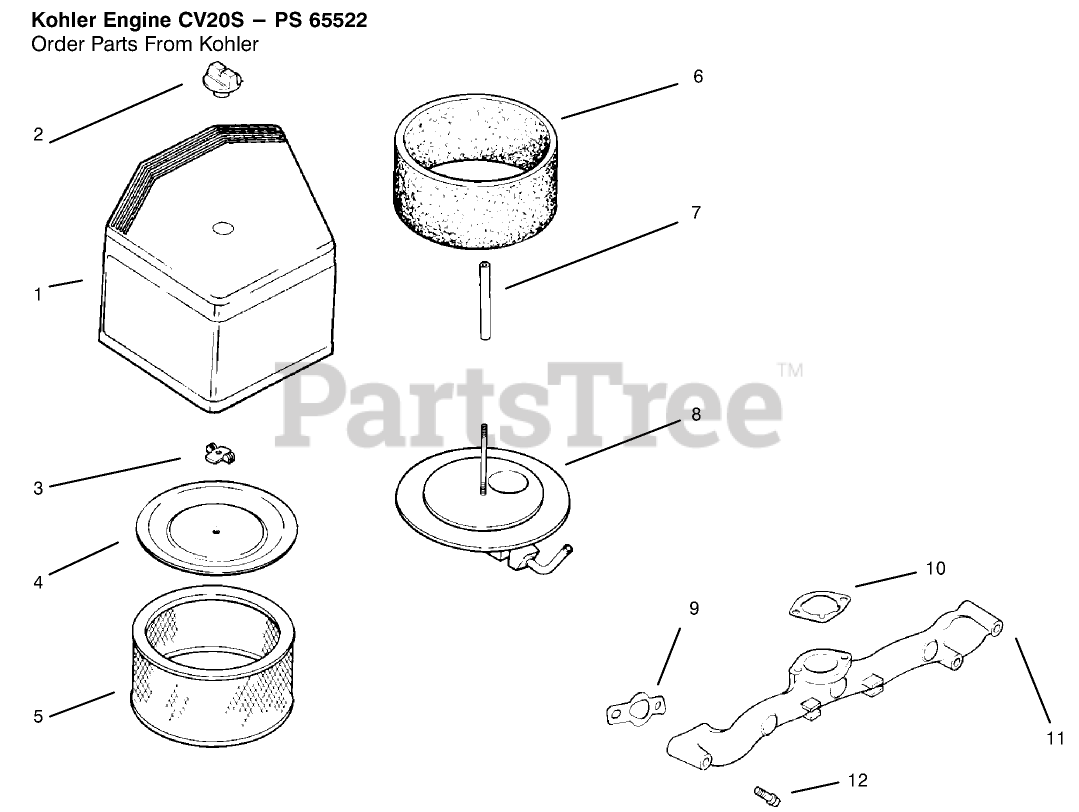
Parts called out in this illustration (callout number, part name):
1	Kit-Air Cleaner Cover (Incl. Ref.# 2)
2	Knob-Cover
3	Wingnut
4	Cover-Element
5	Precleaner
6	Element
7	Seal
8	Elbow-Air Cleaner
9	Gasket-Intake, Manifold
10	Gasket-A/C Base
11	Manifold-Intake
12	Screw
